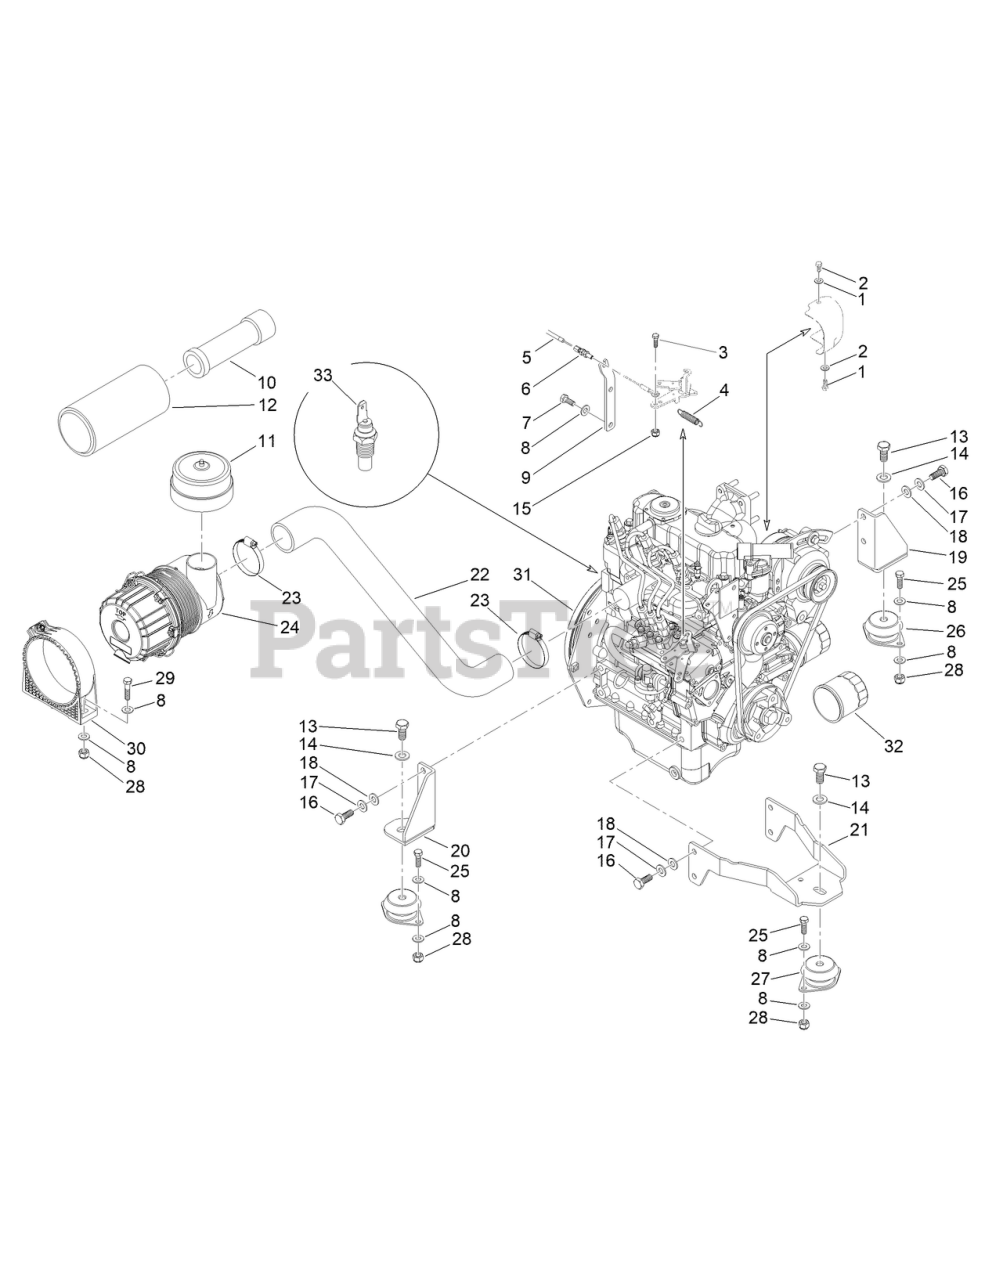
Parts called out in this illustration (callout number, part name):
1	SCREW-HH, CAP
2	WASHER
4	SPRING
5	CABLE, THROTTLE
6	SCREW HH
8	WASHER
9	BRACKET, THROTTLE CABLE
10	ELEMENT-AIR FILTER, INNER
11	PREFILTER-AIR
12	CARTRIDGE-FILTER
14	WASHER
17	WASHER
18	WASHER
19	SUPPORT-FRONT, ENGINE RH
20	SUPPORT-FRONT, ENGINE LH
21	ENGINE SUPPORT, REAR
22	HOSE, ENGINE INTAKE
24	FILTER-AIR
26	SHOCK ABSORBER
27	SHOCK ABSORBER
31	ENGINE
32	OIL-FILTER
33	SENSOR, COOLANT-TEMP
